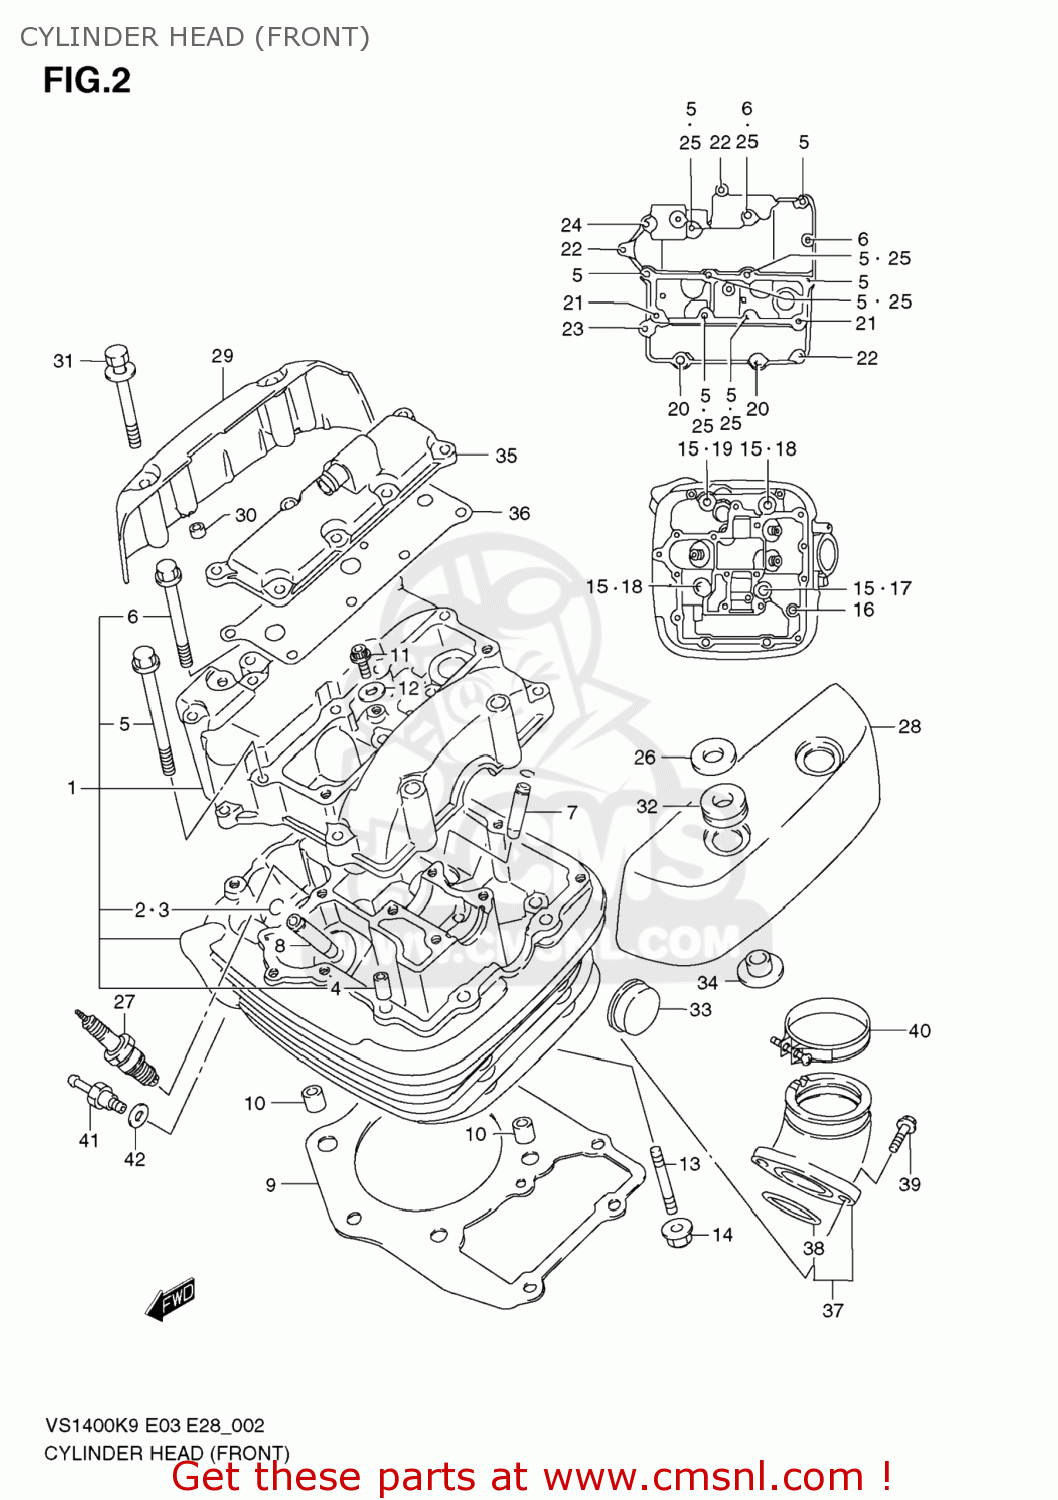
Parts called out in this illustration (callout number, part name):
1	HEAD ASSY,CYLINDER FR
2	RING,SNAP
3	RING,SNAP
4	PIN(6.2X8X11)
5	BOLT(6X60)
6	BOLT(6X55)
7	GUIDE,INTAKE VALVE
8	GUIDE,INTAKE VALVE
9	GASKET,CYLINDER HEAD FR (NAS)
10	PIN
11	BOLT
12	GASKET(6.2X13X1.2) (NAS)
13	BOLT,STUD
14	NUT
15	WASHER(10.5X22X2.3)
16	BOLT(8X70)
17	BOLT(10X180)
18	BOLT(10X190)
19	BOLT(10X200)
20	BOLT(8X268)
21	BOLT
22	BOLT
23	BOLT
24	BOLT
25	GASKET(5.8X13X1.2) (NAS)
26	WASHER(8.5X24X1.6)
27	SPARK PLUG X22E
28	CAP,CYLINDER HEAD COVER FL
29	CAP,CYLINDER HEAD COVER FR
30	CUSHION,R CAP
31	BOLT
32	CUSHION
33	PLUG(OD:30)
34	BUSH
35	COVER,BREATHER
36	GASKET,BREATHER COVER (NAS)
37	PIPE ASSY,INTAKE FR
38	O RING(D:2.4,ID:41.7)
39	BOLT
40	CLAMP
41	BOLT UNION
42	GASKET(6.2X13X1.2) (NAS)
